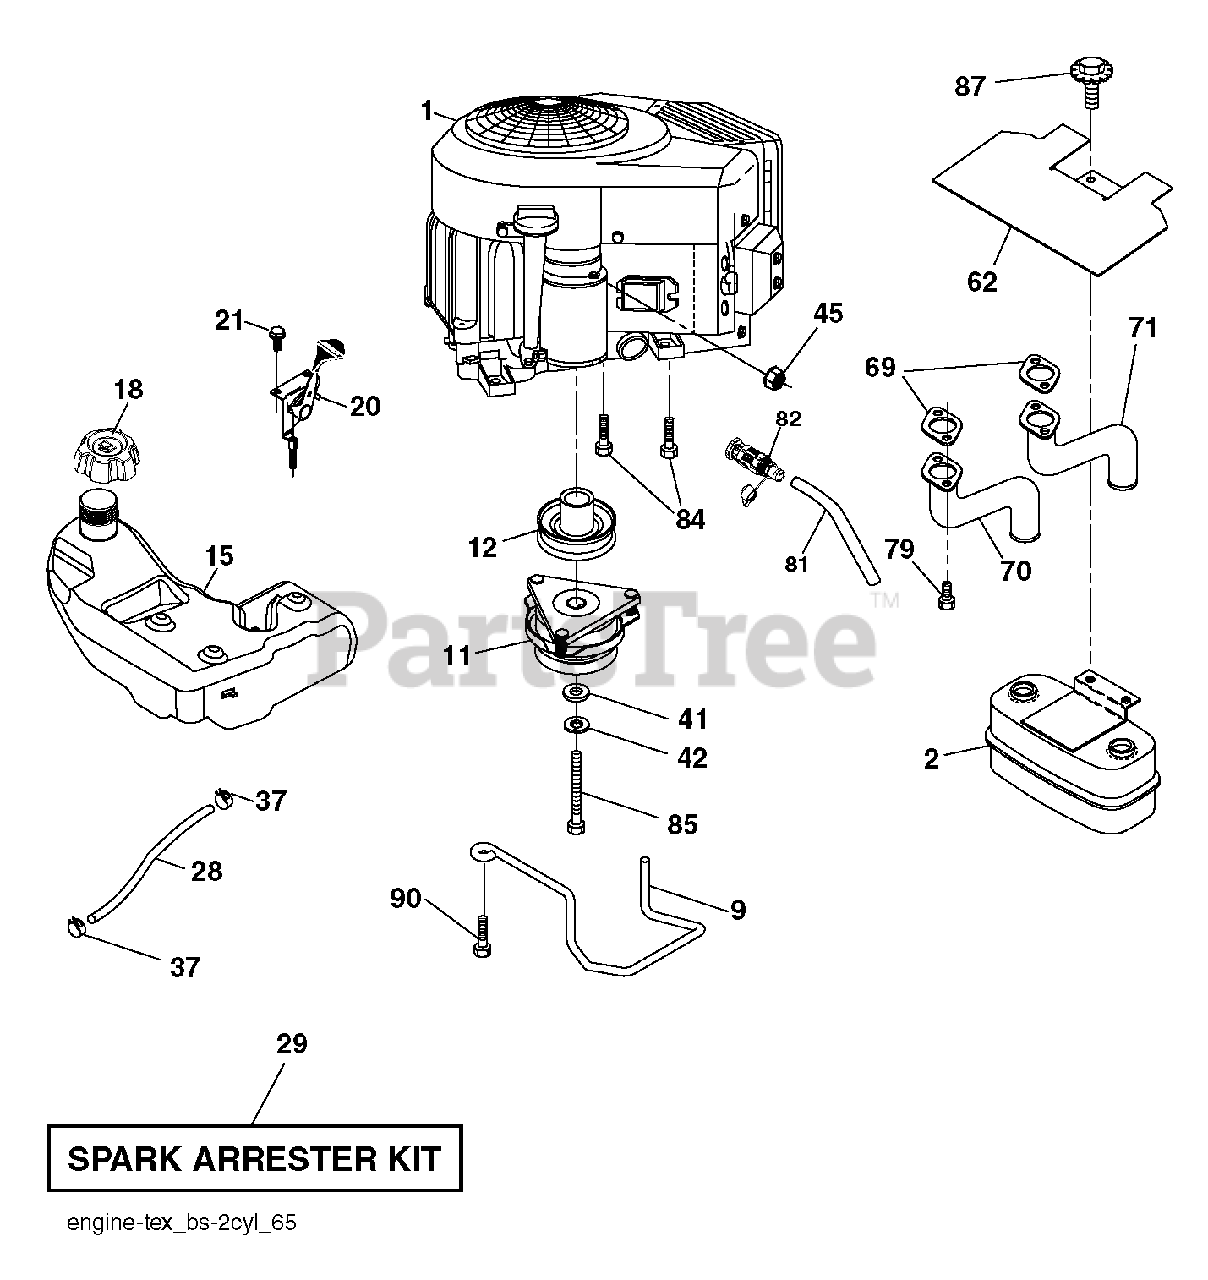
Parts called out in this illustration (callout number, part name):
2	MUFFLER.ASM.TWN.EXTNDED.DFLCTR
9	KEEPER BELT ENGINE
11	CLUTCH.ELECTRIC.LT.48"*
12	PULLEY.ENGINE.TUFFTORQ
15	TANK.ASSY.3.GAL.EPA
18	CAP.ASM.FL.RITCH.3"E10.SYM.498
20	CONTROL.TH/CK.COBRA.B&S.TWN.
21	SCREW.#10 X 0.750.BOS
28	LINE.FUEL.64"REAR.EMIS
29	KIT.SPARK ARRESTOR 794945 B&S
37	HOSE CLAMP
42	LOCKWASHER
45	NUT
62	SHIELD.HEAT.MUFFLER
69	GASKET.MUFFLER
70	EXHAUST.TUBE.LH.BS/TWIN
71	EXHAUST.TUBE.RH.B&S.TWIN.INTEK
79	SCREW.SOCKET.HEAD.5/16-18
81	TUBE, DRAIN OIL ASM.
82	VALUE.OIL.DRAIN
84	SCREW 3/8-16X1
85	BOLT HEX 7/16-20X4-1/4"
87	BOLT, 5/16-18 X 1 3/4
90	SCREW 3/8-16X1
